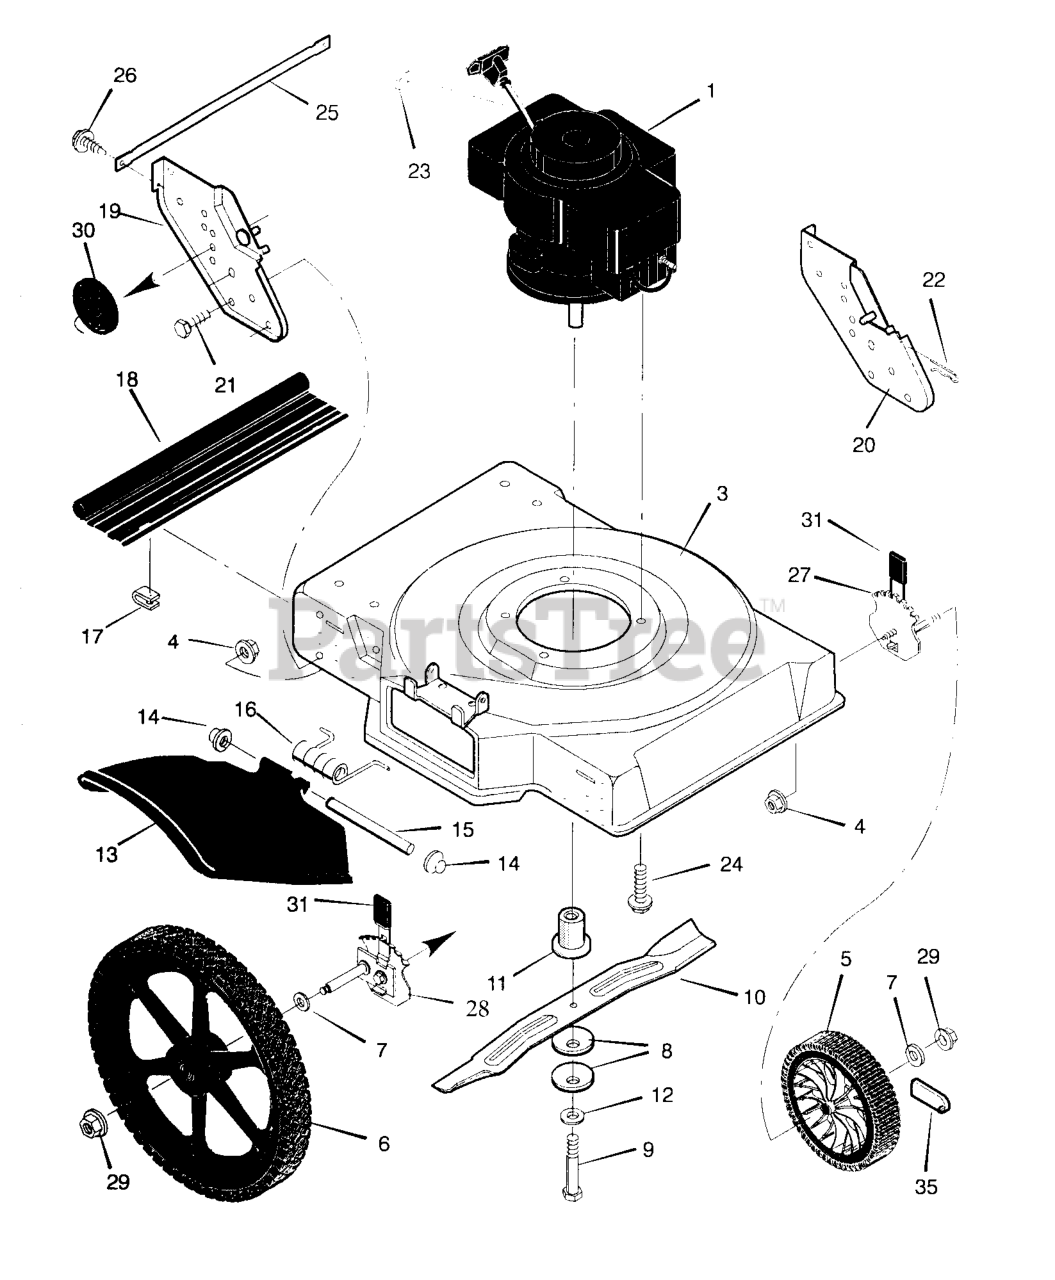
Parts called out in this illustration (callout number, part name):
1	Engine *
3	Housing
4	Nut, Hex
5	Wheel and Tire, Front *
6	Wheel and Tire, Rear *
8	Washer, Blade
9	Bolt, Hex
11	Blade Adapter
13	Deflector, Chute
14	Push On Cap
15	Pin, Pivot
17	Retainer
18	Deflector, Rear
19	Bracket, Right Wheel
20	Bracket, Left Wheel
21	Bolt, Hex
22	Pin, Hair
23	Stop, Rope
24	Bolt, Engine
27	Height Adjuster, Front
28	Height Adjuster, Rear
29	Locknut
35	Hub Cap
